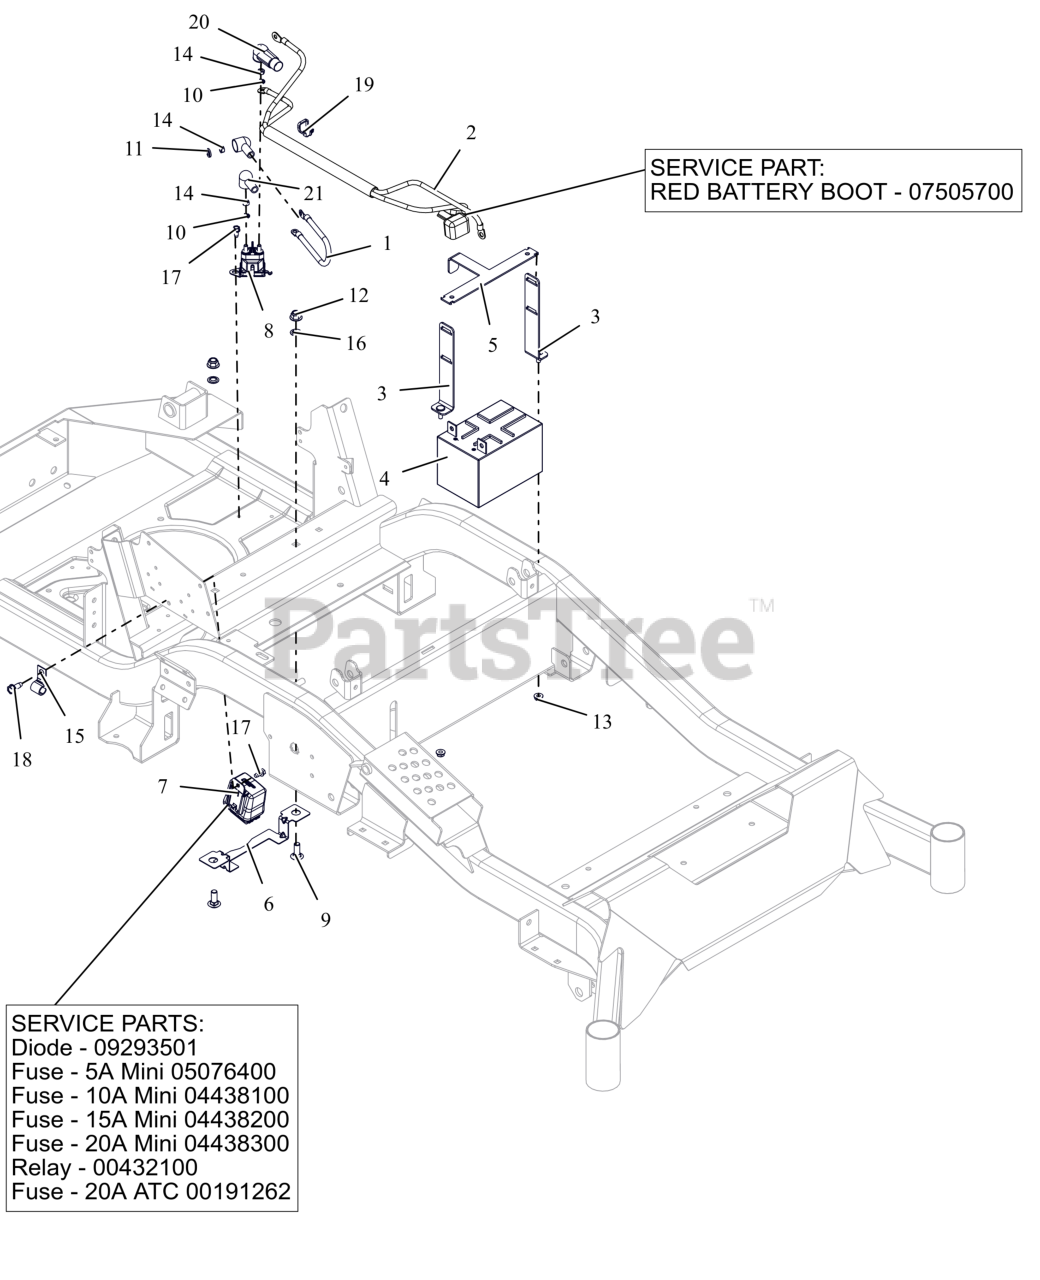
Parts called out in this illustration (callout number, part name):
1	CABLE, POS W/(2)1/4 RING 9.0LG
2	HARNESS, BATTERY HD
2	INSULATOR
3	WMT,BATTERY MOUNT HOLD DOWN
4	BATTERY, 12V 12A-190CCA
5	BRKT, BATTERY TIE DOWN
6	GUARD, ELECTRICAL HARNESS
7	HARNESS, WIRE
7	DIODE, CONNECTOR SHELL
7	FUSE, 5 AMP MINI-ATC
7	FUSE,10 AMP MINI-ATC
7	Fuse, 15 AMP MINI-ATC
7	FUSE,20 AMP MINI ATC
7	RELAY,SEALED W/DIODE
7	FUSE, 20 AMP BLADE S/O
8	SOLENOID, STARTER (SEALED)
9	BLT, RHSN .38-16X1.00 G5 ZCC
10	WSHR,LK-EXT.262X.502X.026 ZCC
11	WSHR,LK-REG .312X.078 ZCC
12	NUT,NYL-FLG .38-16 GF ZCC
13	NUT-LK-TOP-FLG .250-20 GF ZCC
14	NUT-STD M6-1.0 ZCC
15	J-CLAMP
16	NUT-PUSH .38 DIA. PAL ZINC
17	SCR-TAP .25-20X.50 HWH ZCC
18	SCR,TAP .312-18X.75 HWH TR ZCC
19	CABLE TIE W/ TREE (.25 HOLE)
20	BOOT, .65ID POS
21	BOOT, EYELET TERMINAL
